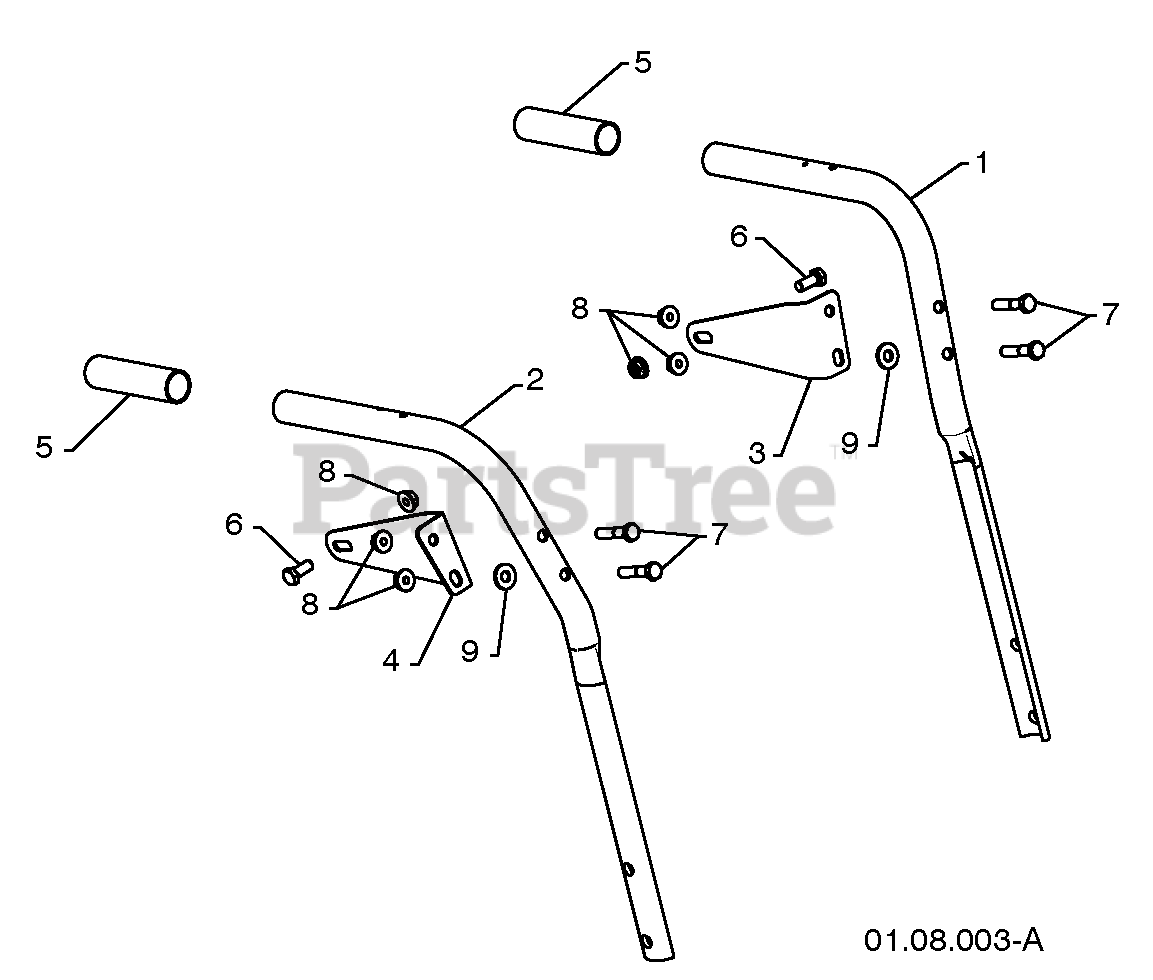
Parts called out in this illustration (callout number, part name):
1	PLOW HANDLE LH
2	PLOW HANDLE RH
3	PANEL BRACKET LH
4	PANEL BRACKET RH
5	HANDLE GRIP
6	SCREW 5/16-18 X .750
7	SCREW 5/16-18 X 1.50
8	NUT 5/16-18
9	WASHER
